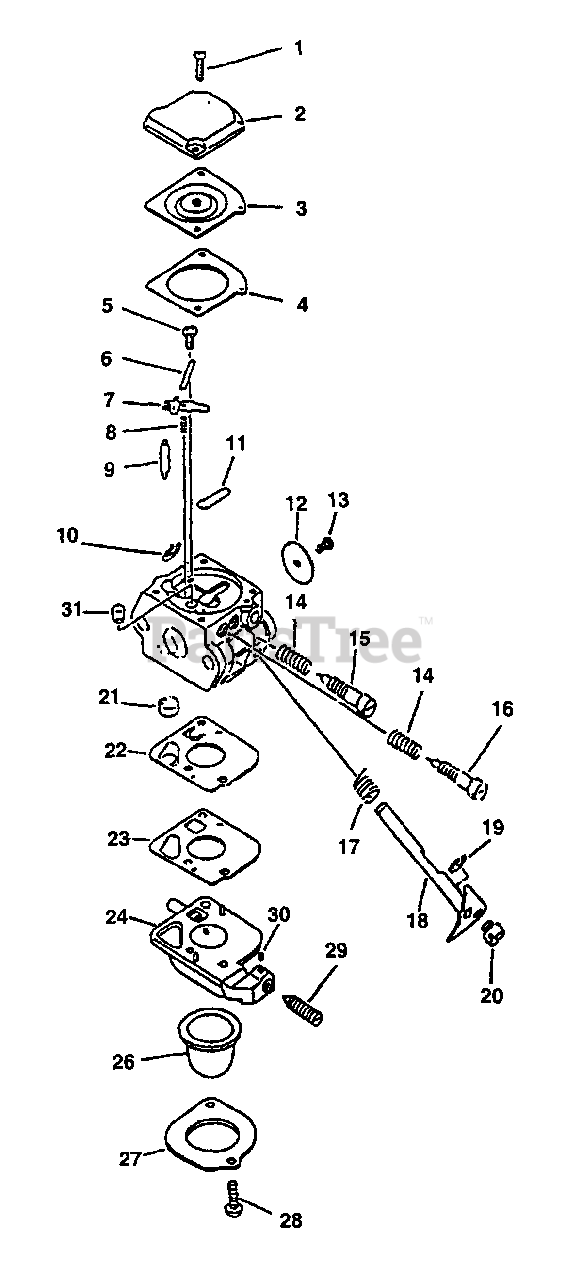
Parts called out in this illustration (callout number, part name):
2	COVER, METERING DIAPHRAGM
3	DIAPHRAGM
4	GASKET, METERING
6	PIN
7	LEVER, METERING
8	SPRING, METERING LEVER
9	VALVE, NEEDLE
11	PLUG, WELCH
12	VALVE, THROTTLE
13	SCREW 3×4.5
14	SPRING, NEEDLE
15	NEEDLE, IDLE
16	NEEDLE, HIGH SPEED
17	SPRING, THROTTLE RETURN
18	SHAFT, THROTTLE
21	STRAINER
24	BODY ASSY, PURGE
26	BULB, PURGE
27	RETAINER
29	SCREW, IDLE ADJUST
30	PIECE, FRICTION
31	NOZZLE, CHECK VALVE
